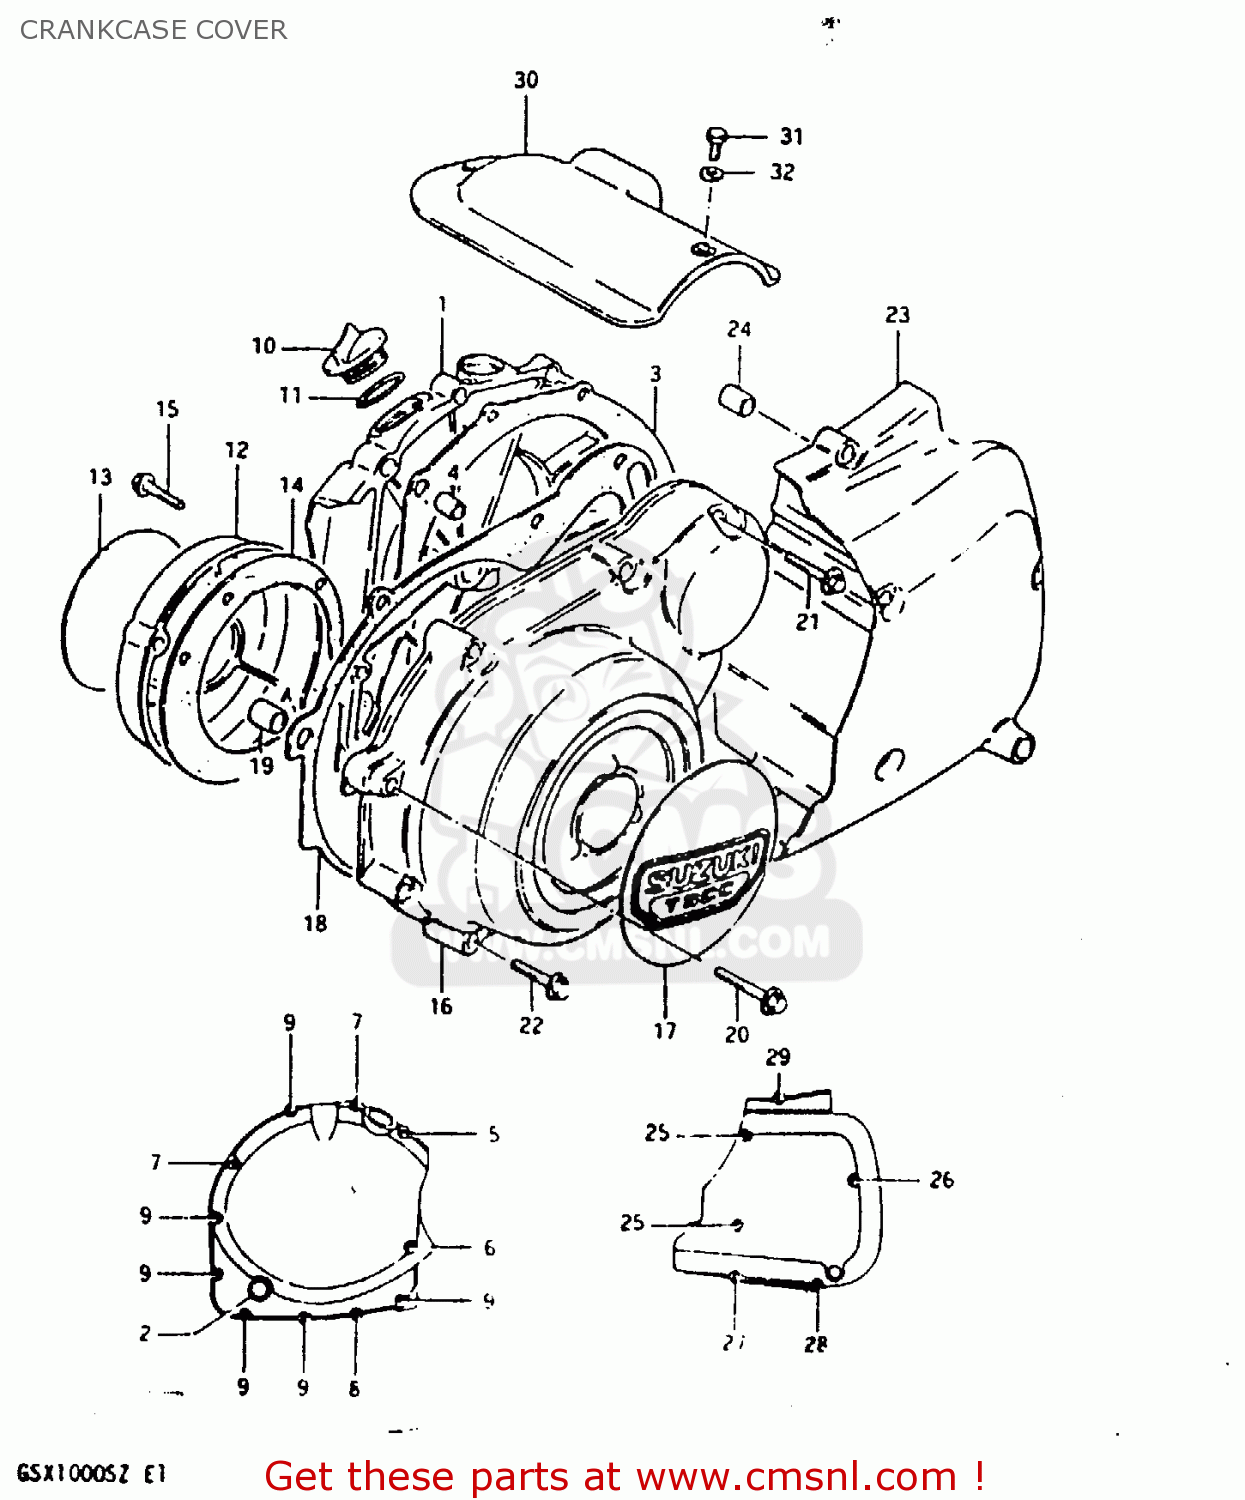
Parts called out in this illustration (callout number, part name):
1	COVER,CLUTCH
2	LENS,OIL LEVEL CHECK
3	GASKET
4	PIN
5	BOLT (6X40)
6	BOLT (6X35)
7	BOLT (6X30)
8	BOLT
9	BOLT (6X20)
10	CAP
11	O RING(D:2.2,ID:32)
12	COVER,CONTACT BREAKER
13	EMBLEM
14	GASKET,CONTACT BREAKER COVER (NAS)
15	BOLT (5*30)
16	COVER,MAGNETO
17	EMBLEM,MAGNETO COVER
18	GASKET,MAGNETO COVER (MCA)
19	PIN
20	BOLT
21	BOLT (6X40)
22	BOLT (6X35)
23	COVER,ENGINE SPROCKET
24	PIN
25	BOLT 6X95
26	BOLT (6X85)
27	BOLT (6X70)
28	BOLT (6X55)
29	BOLT
30	COVER,STARTER MOTOR
31	BOLT
32	WASHER
